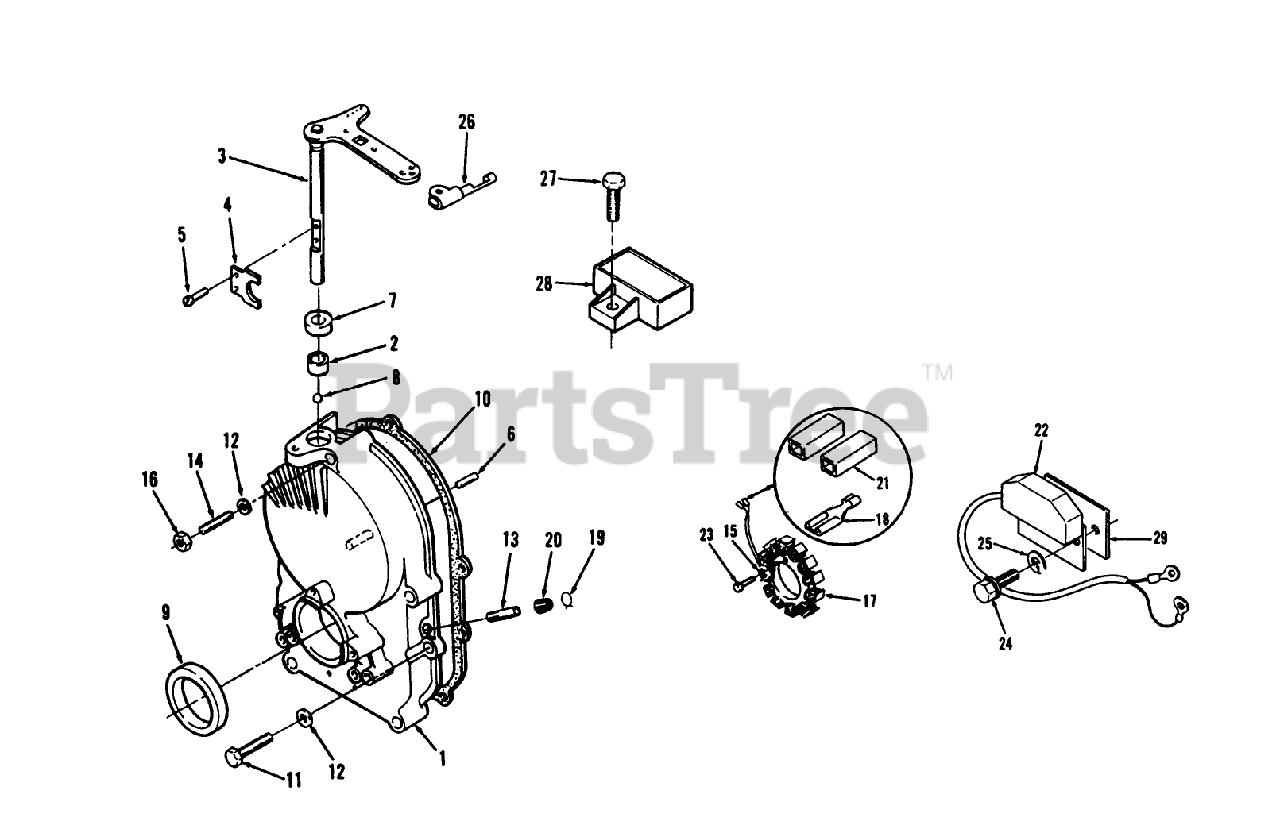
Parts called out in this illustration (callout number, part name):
12	WASHER
21	BODY-TERM. CONNECTOR KIT
25	WASHER-LOCK
27	SCREW-HWH
